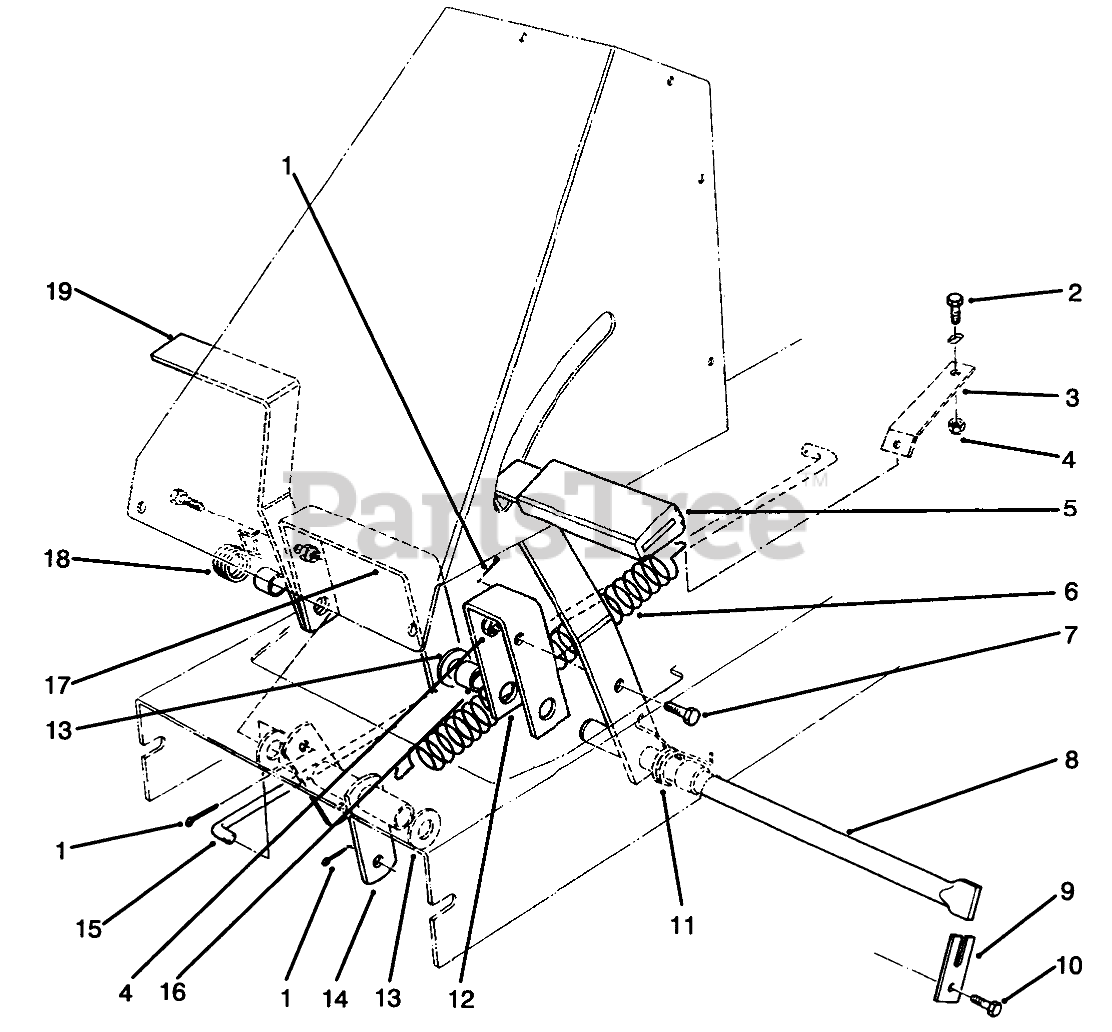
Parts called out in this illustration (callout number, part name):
1	PIN-COTTER
2	SCREW-HH
3	BRKT-SPRING RET
4	NUT-LOCK, NI
5	PAD-PEDAL
6	SPRING-EXTENSION
7	SCREW-HH
8	SHAFT-PEDAL PIVOT
9	RETAINER-SHAFT
10	SCREW-HH
11	SPRING-TORS CLUTCH
12	Bracket-Clutch Pedal
13	WASHER-FLAT
14	Pivot Tube
15	ROD-ENGAGE
16	SPACER-PEDAL
17	Bracket-Brake Pedal
18	SPRING-TORS BRAKE
19	Pedal
